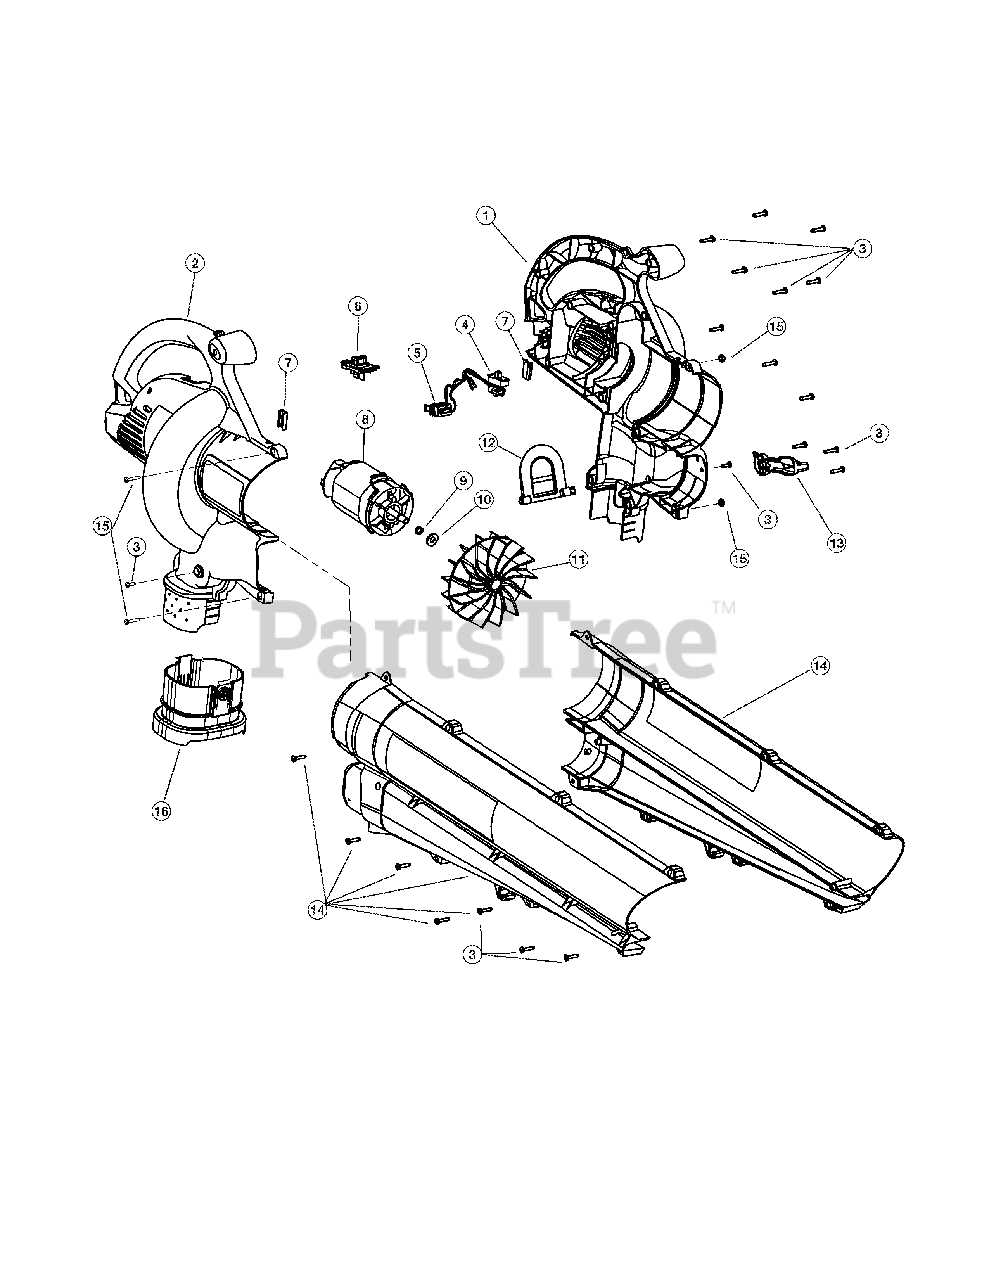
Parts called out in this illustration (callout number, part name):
1	Left Motor Housing
2	Right Motor Housing
3	Housing Screw
4	Switch Assembly
5	Power Connection Wire Assembly
6	Switch Lever
7	Rubber Cushion
8	Motor Assembly
11	Impeller
12	Mode Control Flapper
13	Mode Control Lever (includes 3)
14	Blower/Vac Tube Assembly (includes 3)
15	Blower/Vac Tube Mounting Hardware
16	Vacuum Bag Adapter
